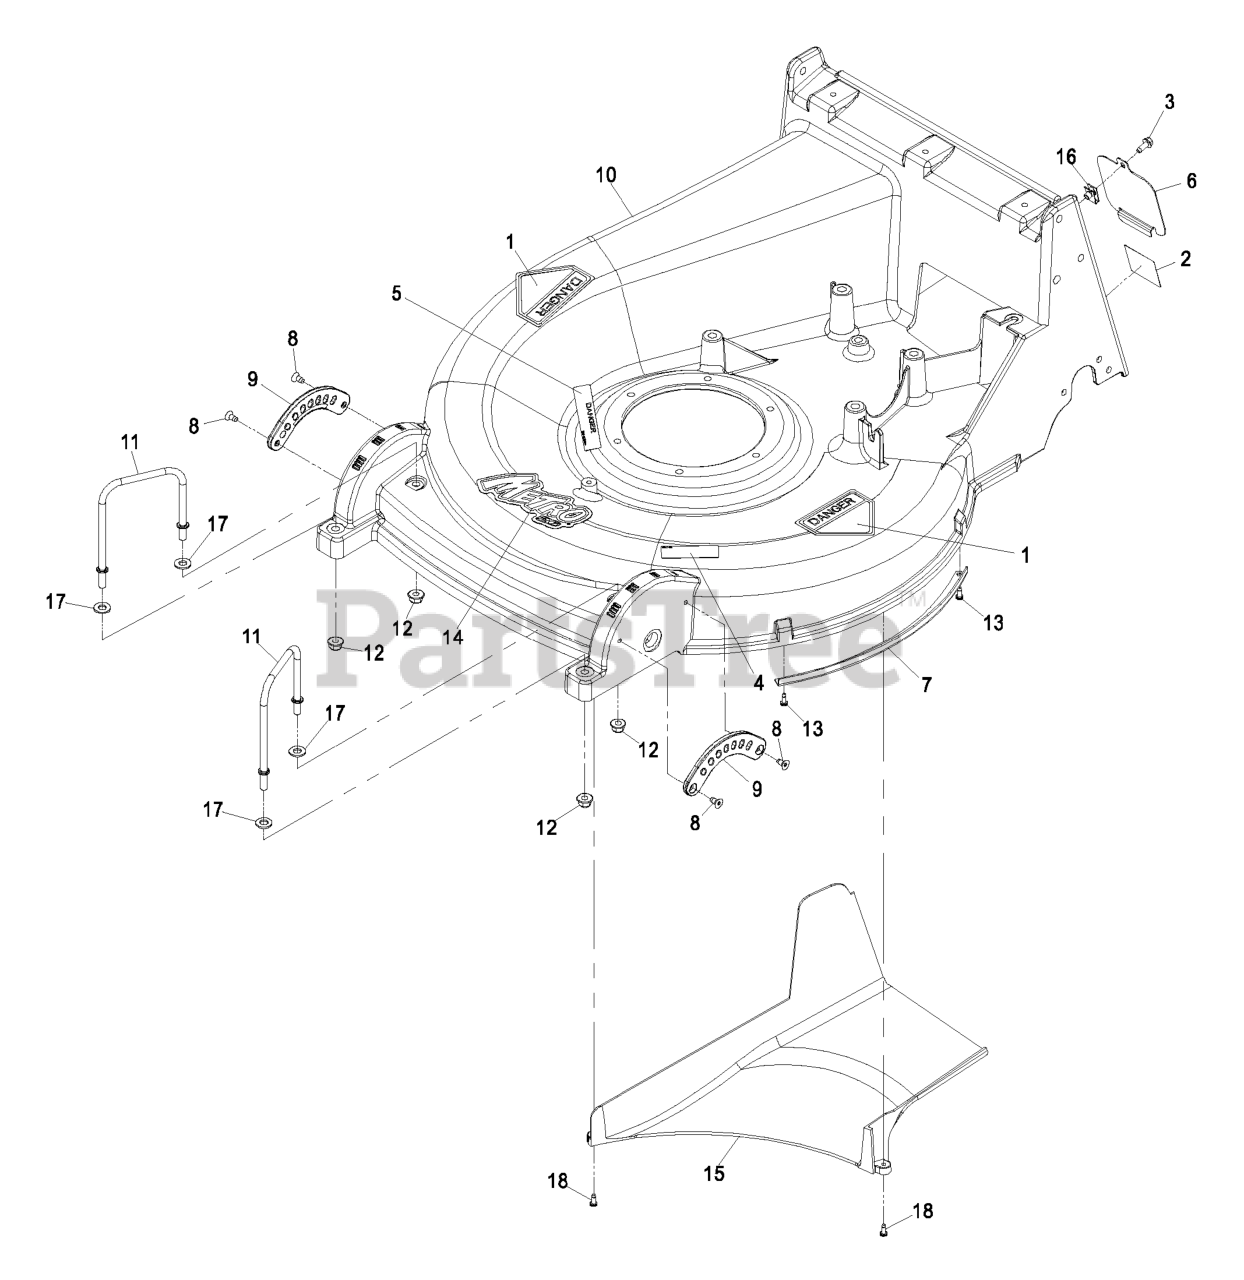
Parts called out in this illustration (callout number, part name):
1	DECAL-DANGER
2	DECAL,SERVICE M26
3	SCREW-HWH
4	DECAL-BLADE
5	DECAL-COVER, MISSING
7	GUARD-EDGE
9	QUADRANT-FRONT
10	ASM,26 DECK W/DECALS
12	NUT-HF, NI
13	SCREW-FORMING, THREAD
14	DECAL,METRO 26
16	Nut, Retainer-Panel 1/4-20
17	WASHER-FLAT
18	SCREW-TORX
